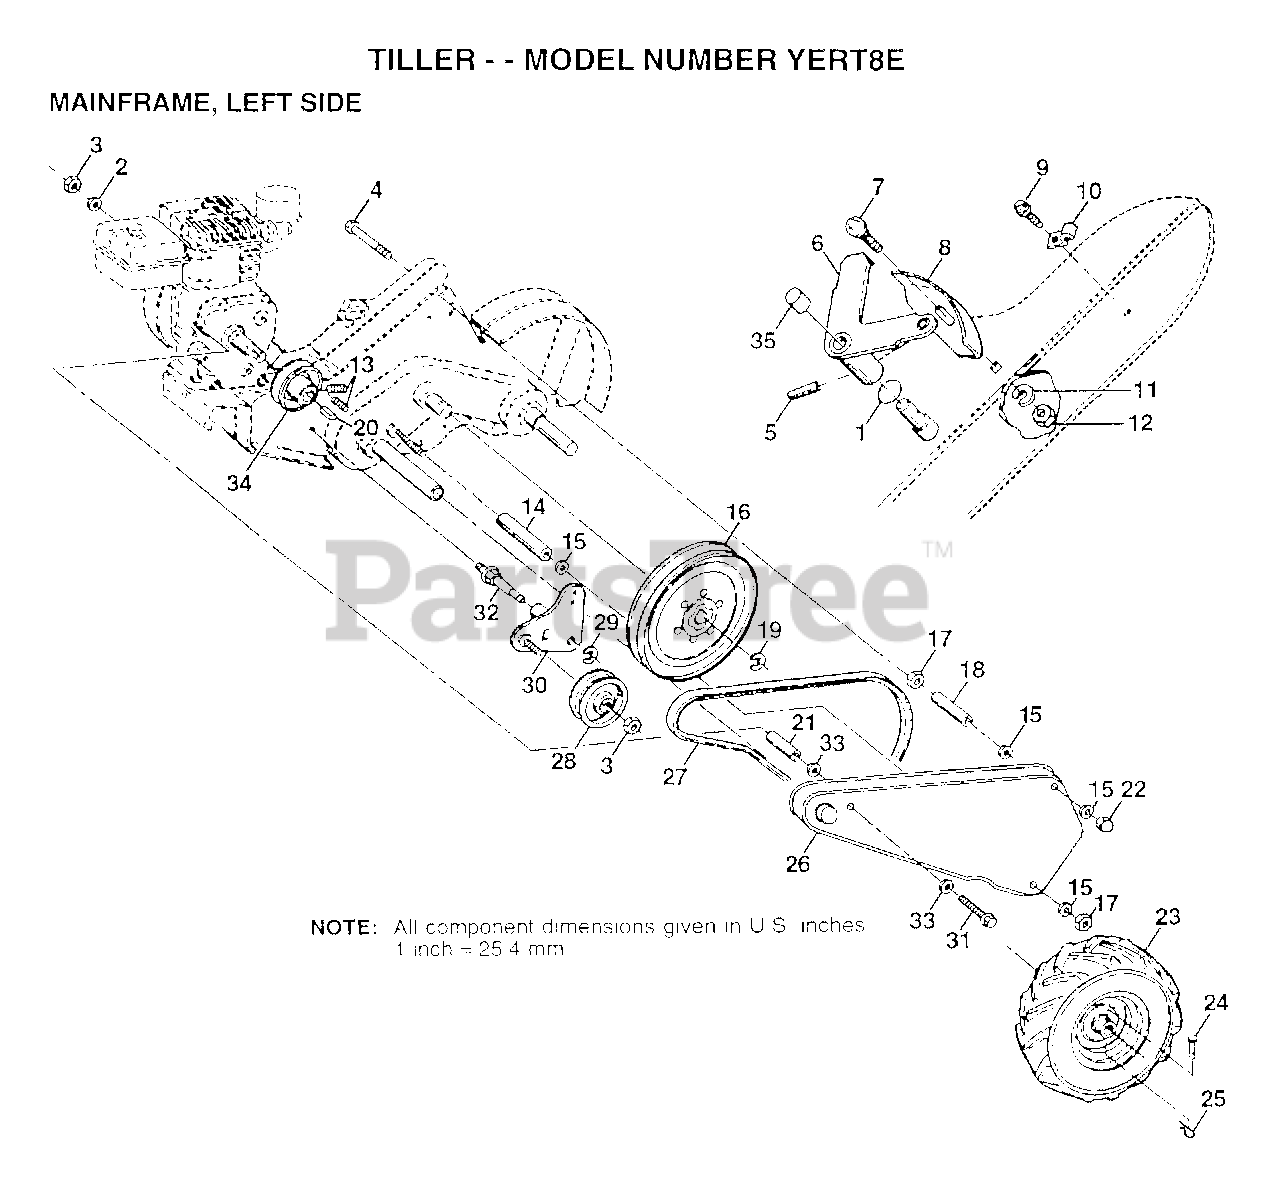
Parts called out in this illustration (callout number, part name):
1	O-RING TI
2	LOCKWASHER
3	NUT.HEX.3/8-16UNC
4	BOLT TI
6	LEVER ASM CRT
7	BOLT
8	PANEL TI
10	CONDIUT CLIP T
11	LOCKWASHER
13	SET SCREW
14	SPACER TI
15	WASHER
16	SHEAVE.TRANS.
17	NUT.HEX.5/16-18
18	SPACER TI
20	KEY TI
21	SPACER.SPLIT
22	NUT TI
23	TIRE TI
24	RIVET.PAN HD.1.75
25	SPRING.RETAINER
26	GUARD BELT RED
27	BELT.DRIVE
29	KLIP RING
31	BOLT1/2-20UNF2.75
32	SHAFT.IDLER
34	SHEAVE CRT
35	CAP PLUNGER BLACK
